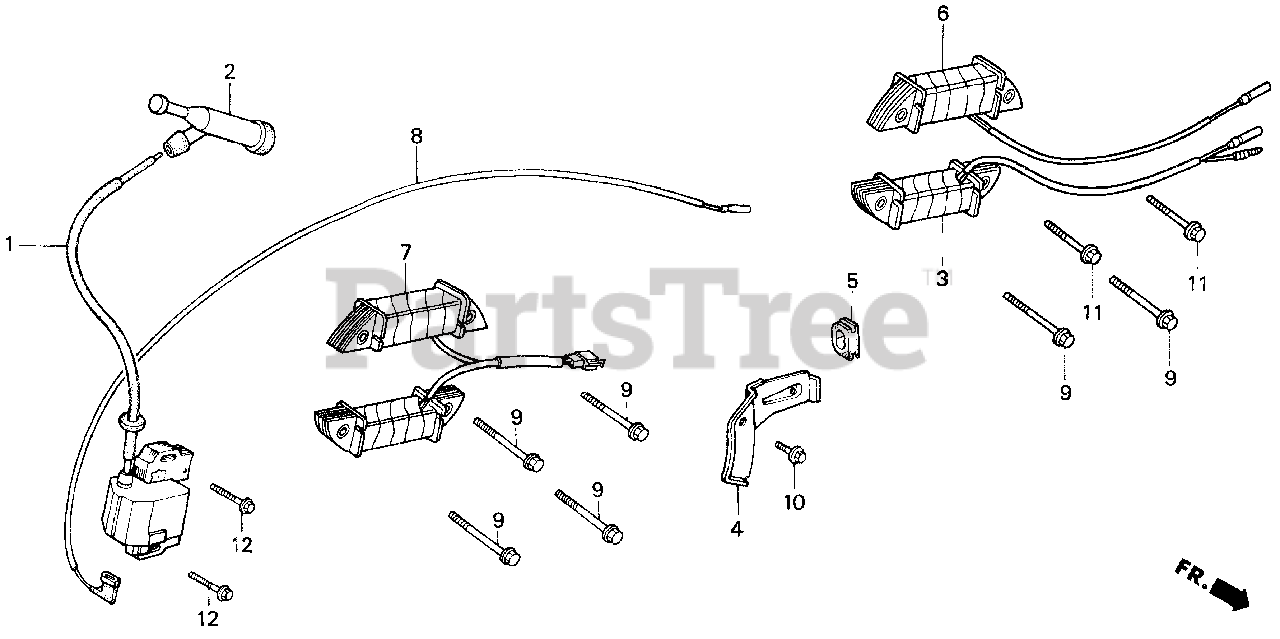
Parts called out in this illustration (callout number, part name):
1	COIL ASSY., IGNITION
2	CAP ASSY., NOISE SUPPRESSOR
5	GROMMET, WIRE
8	WIRE, STOP SWITCH (430MM)
12	BOLT, FLANGE (6X28)
